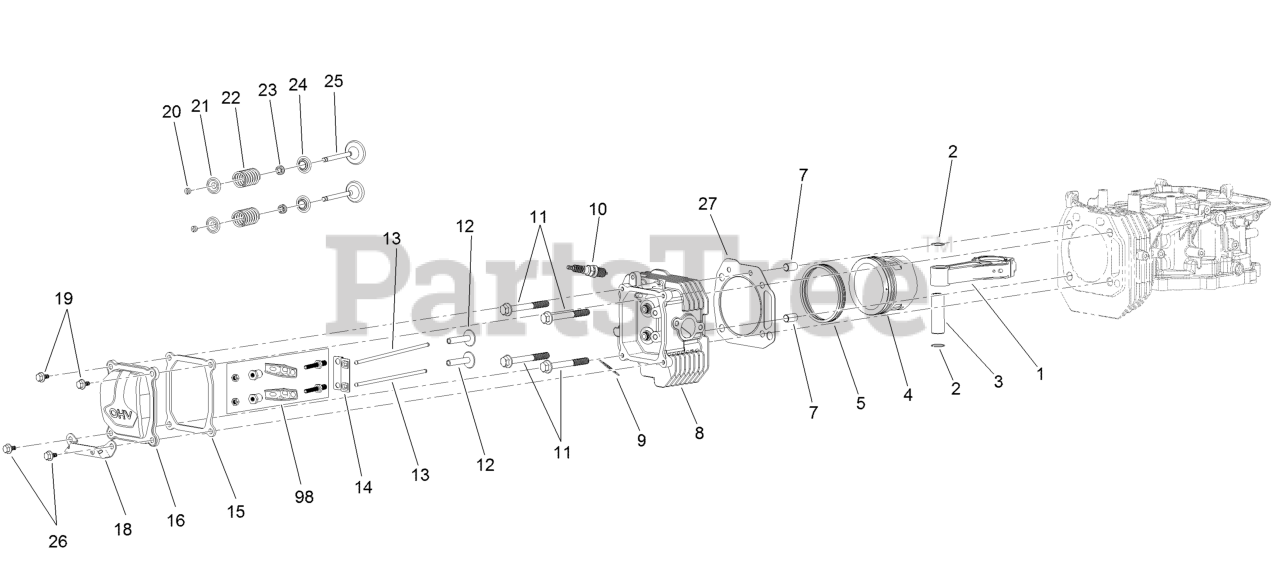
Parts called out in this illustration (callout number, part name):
1	CONNECTING ROD ASM
2	RING-RETAINING, PISTON PI
3	PIN-PISTON
5	RING SET
7	PIN-DOWEL
8	HEAD-CYLINDER
9	GASKET-EXHAUST
10	Plug-Spark
11	SCREW-HHF
12	LIFTER-VALVE
13	ROD-PUSH
14	PLATE-GUIDE, PUSH ROD
15	GASKET-COVER, VALVE
16	COVER-VALVE
18	BRACKET-MUFFLER
19	SCREW-SHOULDER, HHF
20	KEEPER-VALVE
21	RETAINER-SPRING, VALVE
22	SPRING-VALVE
23	SEAL-STEM, VALVE
24	SEAT-SPRING, VALVE
25	VALVE SET
26	SCREW-SHOULDER, HHF
27	GASKET-CYCLINDER
